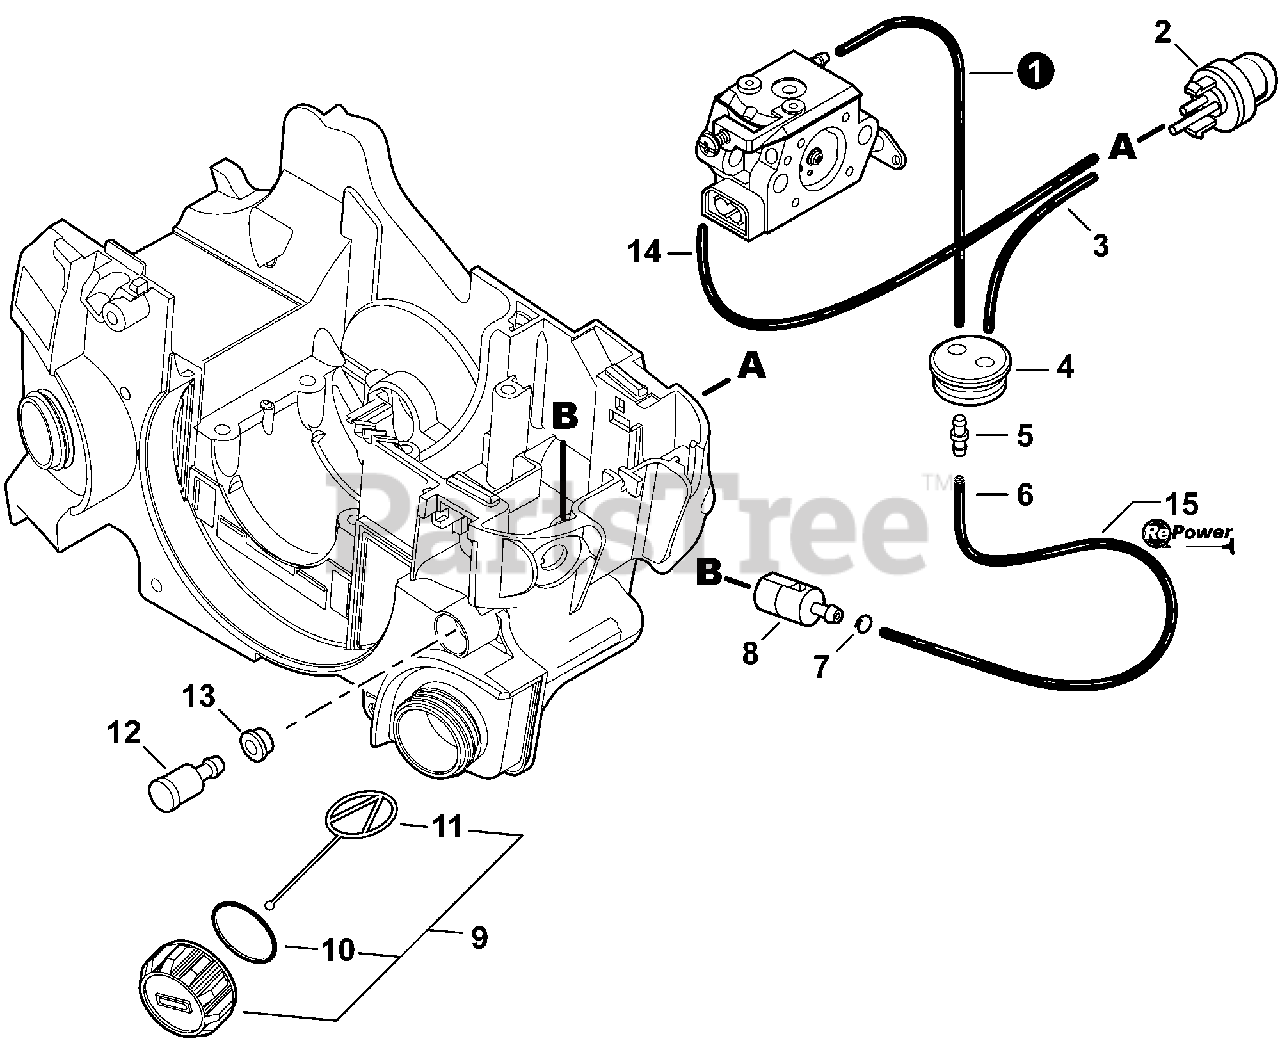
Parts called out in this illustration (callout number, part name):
1	PIPE, FUEL 3×5×85 BLACK
2	BULB, PURGE
3	PIPE, FUEL RETURN 2.4×5×80 BLACK
4	GROMMET, FUEL
5	CONNECTOR, PIPE
6	PIPE, FUEL 3×5×144 BLACK
8	FILTER, FUEL
9	CAP ASSY, FUEL
10	O-RING 22
11	CONNECTOR, CAP L= 60mm
12	VENT ASSY
13	GROMMET, FUEL
14	PIPE 2.4×5×125 BLACK
15	PIPE, FUEL - REPOWER BULK 3×5mm BLACK
